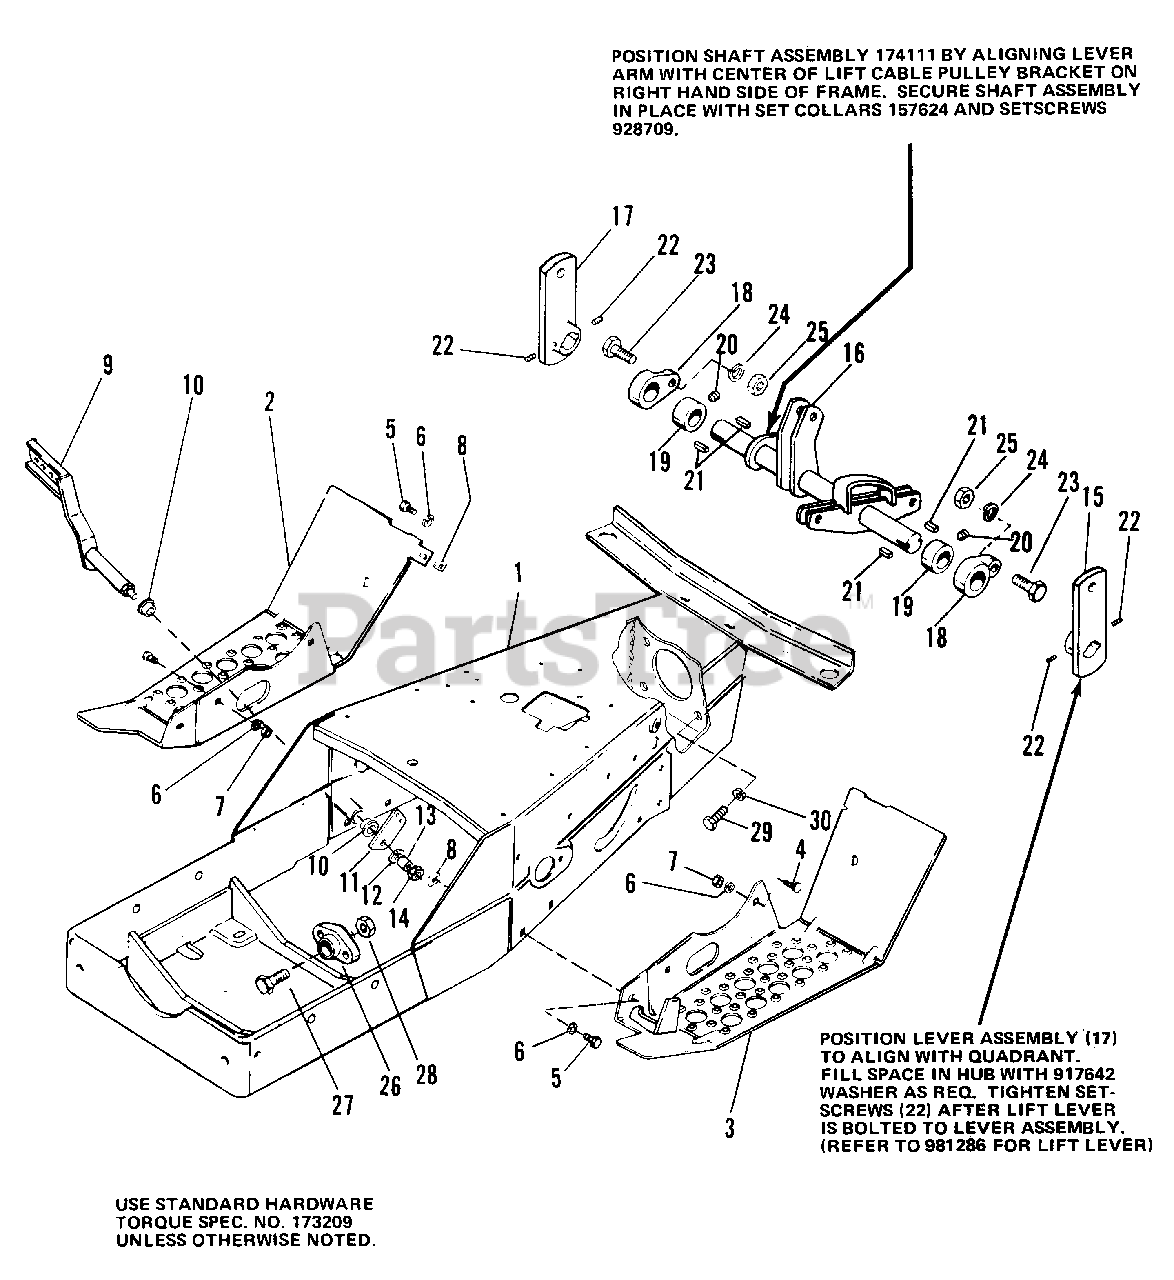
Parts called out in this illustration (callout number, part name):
1	REAR FRAME ASSEMBLY
2	FOOT REST, R.H.
3	FOOT REST, L.H.
4	BOLT, Carriage, 5/16-18 x 3/4
5	CAPSCREW, Hex Hd., 5/16-18 x 3/4
6	LOCKWASHER, 5/16
7	NUT, Hex, Full, 5/16-18
8	NUT, Speed, Tinn., 5/16-18
9	FOOT PEDAL ASSEMBLY
11	ARM, Pedal Foot
12	WASHER, 3/8
13	LOCKWASHER,3/8
14	NUT, Hex, Full,3/8-16
15	FRONT LIFT LEVER ASSEMBLY
16	LIFT SHAFT ASSEMBLY
17	LIFT LEVER ASSEMBLY
18	BEARING, Lift Lever
19	SET, Collar
20	SETSCREW, Cup Pt., 5/16-18 x 3/8
22	SETSCREW, Soc. Hd., 5/16-18 x 1/4
23	CAPSCREW, Hex Hd., 5/16-18 x 1-1/4
24	LOCKWASHER, 5/16
25	NUT, Hex, Full, 5/16-18
26	BEARING, Pivot
27	CAPSCREW, Whiz, 3/8-16 x 1-1/4
28	NUT, Flange, 3/8-16
29	CAPSCREW, Hex Hd., 7/16-14 x 1-1/2
30	LOCKWASHER, 7/16
